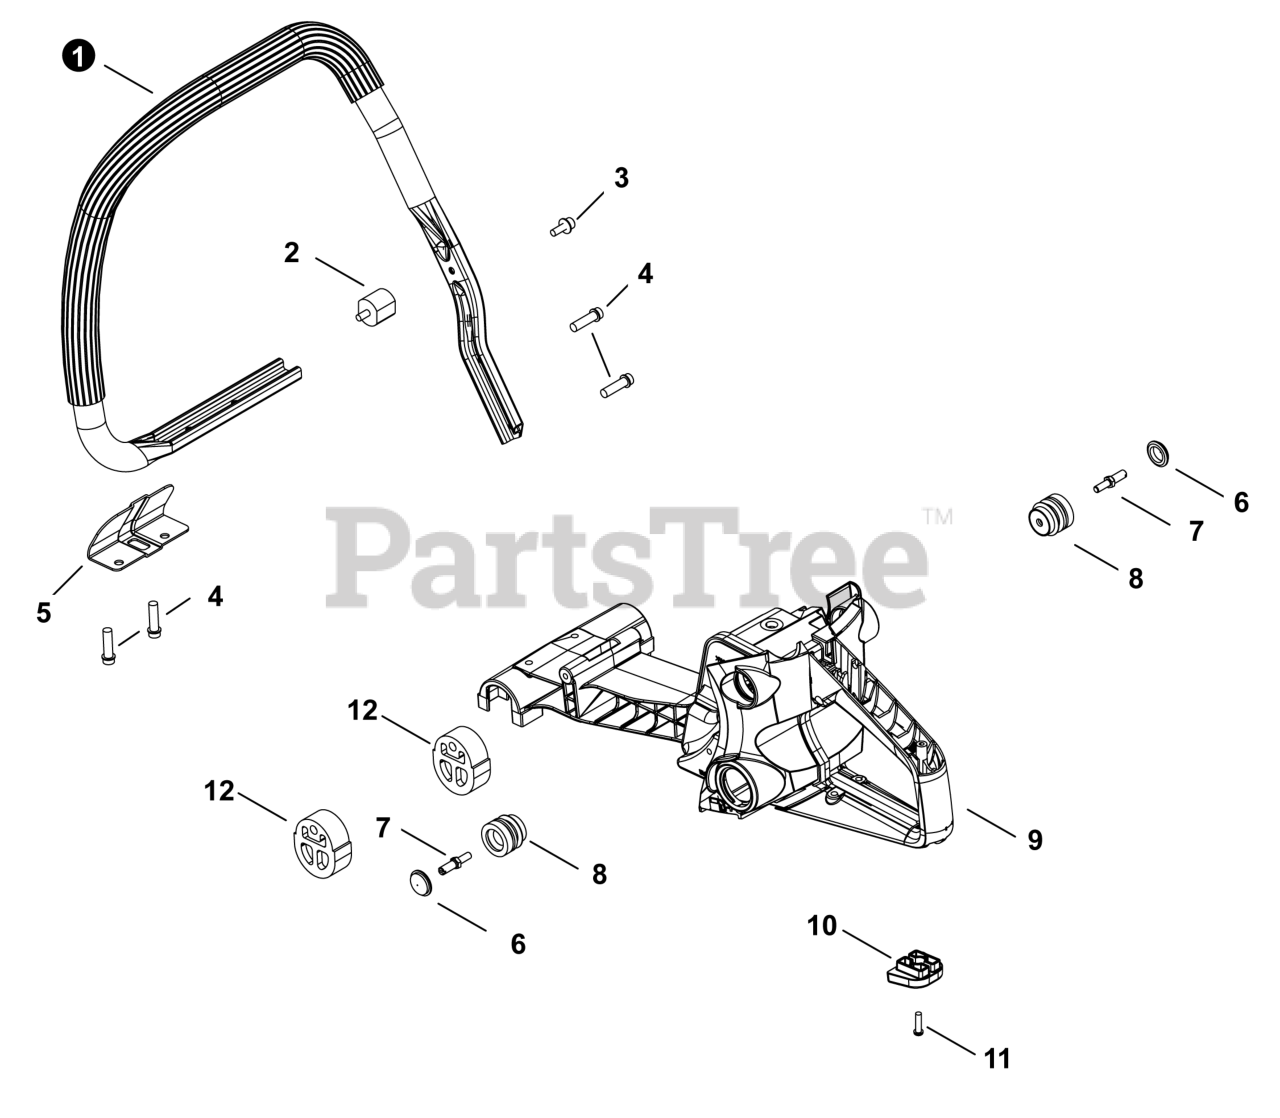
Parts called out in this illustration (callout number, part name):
1	HANDLE, FRONT
2	CUSHION 5
7	BOLT, STOPPER 26
8	CUSHION
9	HANDLE ASSY, REAR
10	CUSHION
11	SCREW 4
12	CUSHION
